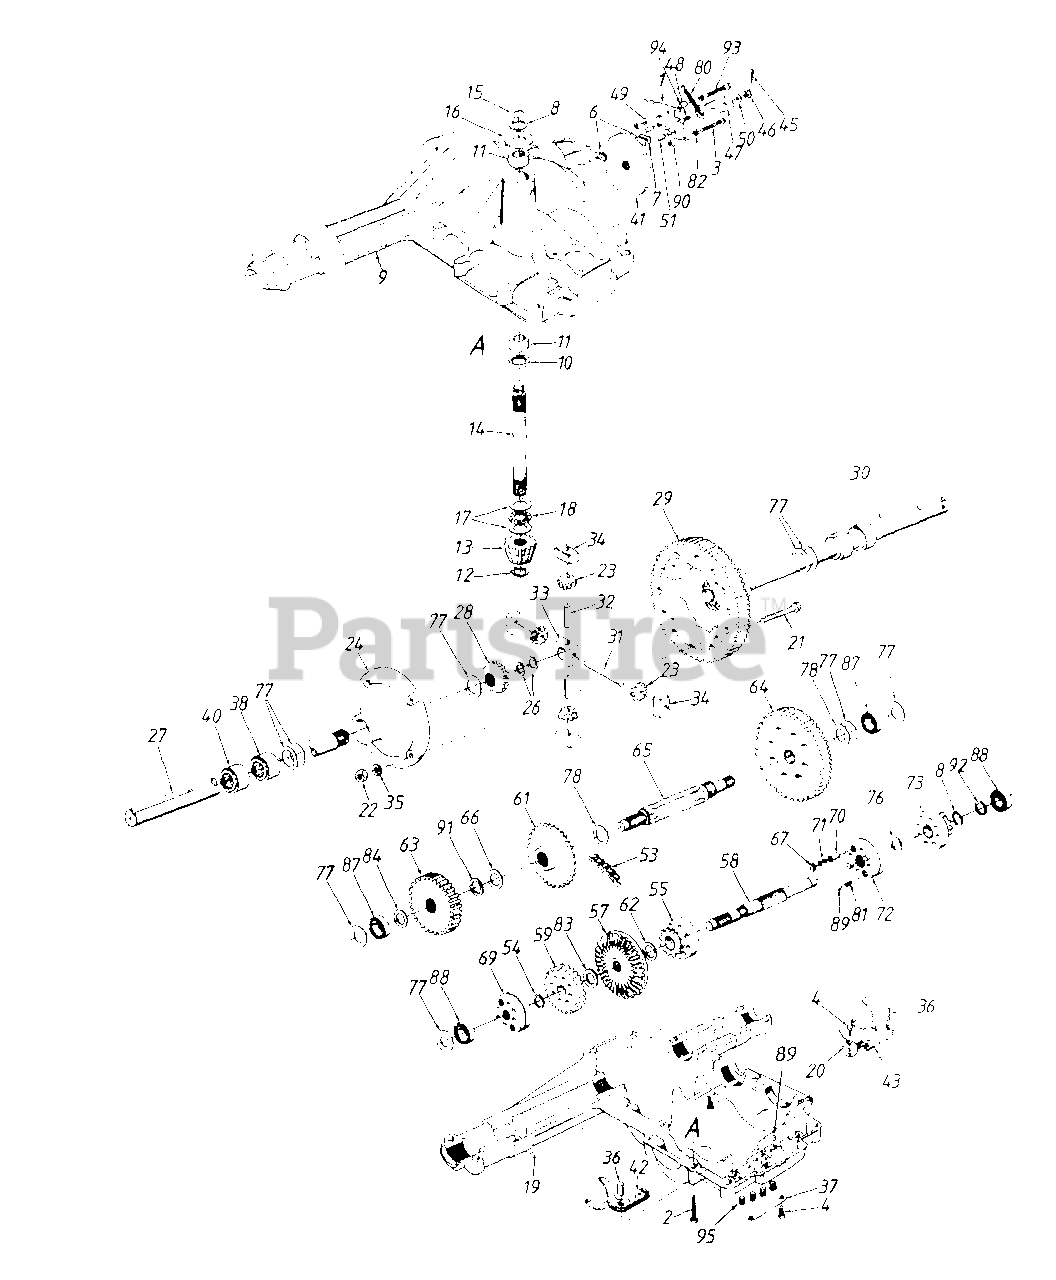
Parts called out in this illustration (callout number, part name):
1	Brake Return Bracket
2	Hex Bolt 1/4-20 x 1.25" Lg.
3	Hex Bolt 1/4-20 x 1.5" Lg. (Gr. 5)
4	Hex Wash. Hd. Tap Scr. 1/4-20 x .5" Lg.
6	Brake Puck
7	Puck Plate
8	Retainer Ring
9	Upper Housing
11	Needle Brg. 5/8" I.D. x 7/8" O.D.
12	Snap Ring
13	Input Pinion 15T
16	Thrust Washer 5/8" I.D.
17	Thrust Washer
18	Thrust Bearing
19	Lower Housing
21	Hex Bolt 3/8-24 x 2.0" Lg.
22	Hex L-Nut 3/8-24 Thd. (Gr. 5)
23	Differential Gear 10T
24	Differential Housing Cover Ass'y.
26	Retainer Ring
28	Differential Gear 14T
29	Differential Bull Gear 60T
32	Cross Shaft - Special
33	Differential Pinion Block
34	Differential Thrust Block
35	Spr. Wash. .39" I.D. x .62" O.D.
37	Spring Plate
38	Axle Bearing Ass'y.
40	Axle Bearing Ass'y.
41	Brake Disc
42	Shift Arm Ass'y. - R.H.
43	Shift Arm Ass'y. - L.H.
45	Cotter Pin 3/32" Dia.
46	Castle Nut 5/16-24 Thd.
47	Brake Actuating Arm
48	Sq. Hd. Bolt 5/16-24 Thd.
50	Fl-Wash. 11/32" I.D. x 7/8" O.D.
51	Brake Actuating Pin
53	#420 Chain 1/2 Pitch x 28 Links
54	Retainer Ring
55	Reverse Sprocket Ass'y.
57	Bevel Gear 47T
59	Spur Gear Ass'y.
61	Sprocket 22T
62	Fl-Wash. .81" I.D. x 1.18" O.D.
63	Spur Gear 31T
64	Spur Gear 45T
65	Output Shaft 9T
67	Shift Spring Plug
69	Forward Shift Collar
70	Drive Pin
72	Creeper Shift Collar
73	Creeper Collar Plate Ass'y.
76	Fl-Wash. .65" I.D. x .97" O.D.
77	Fl-Wash.
78	Fl-Wash. 1.0" I.D. x 1.56" O.D.
80	Ext. Spring 1.14" Lg.
81	Detent Spring
82	L-Wash. 1/4" I.D.
83	Fl-Wash. 5/8" I.D. x 1.0" O.D.
84	Fl-Wash. .68" x 1.12"
87	Ball Brg. .669" I.D.
88	Ball Bearing
89	Ball Detent .25" Dia.
90	Spacer .254" I.D. x .5" O.D.
91	Fl-Wash. .69" I.D. x 1.06" O.D.
92	Fl-Wash.
93	Hex Wash. Hd. Patch Bolt 1/4-20 x 2-1/4" Lg.
94	Spacer .256" I.D. x .75" O.D.
95	Detent Spring
